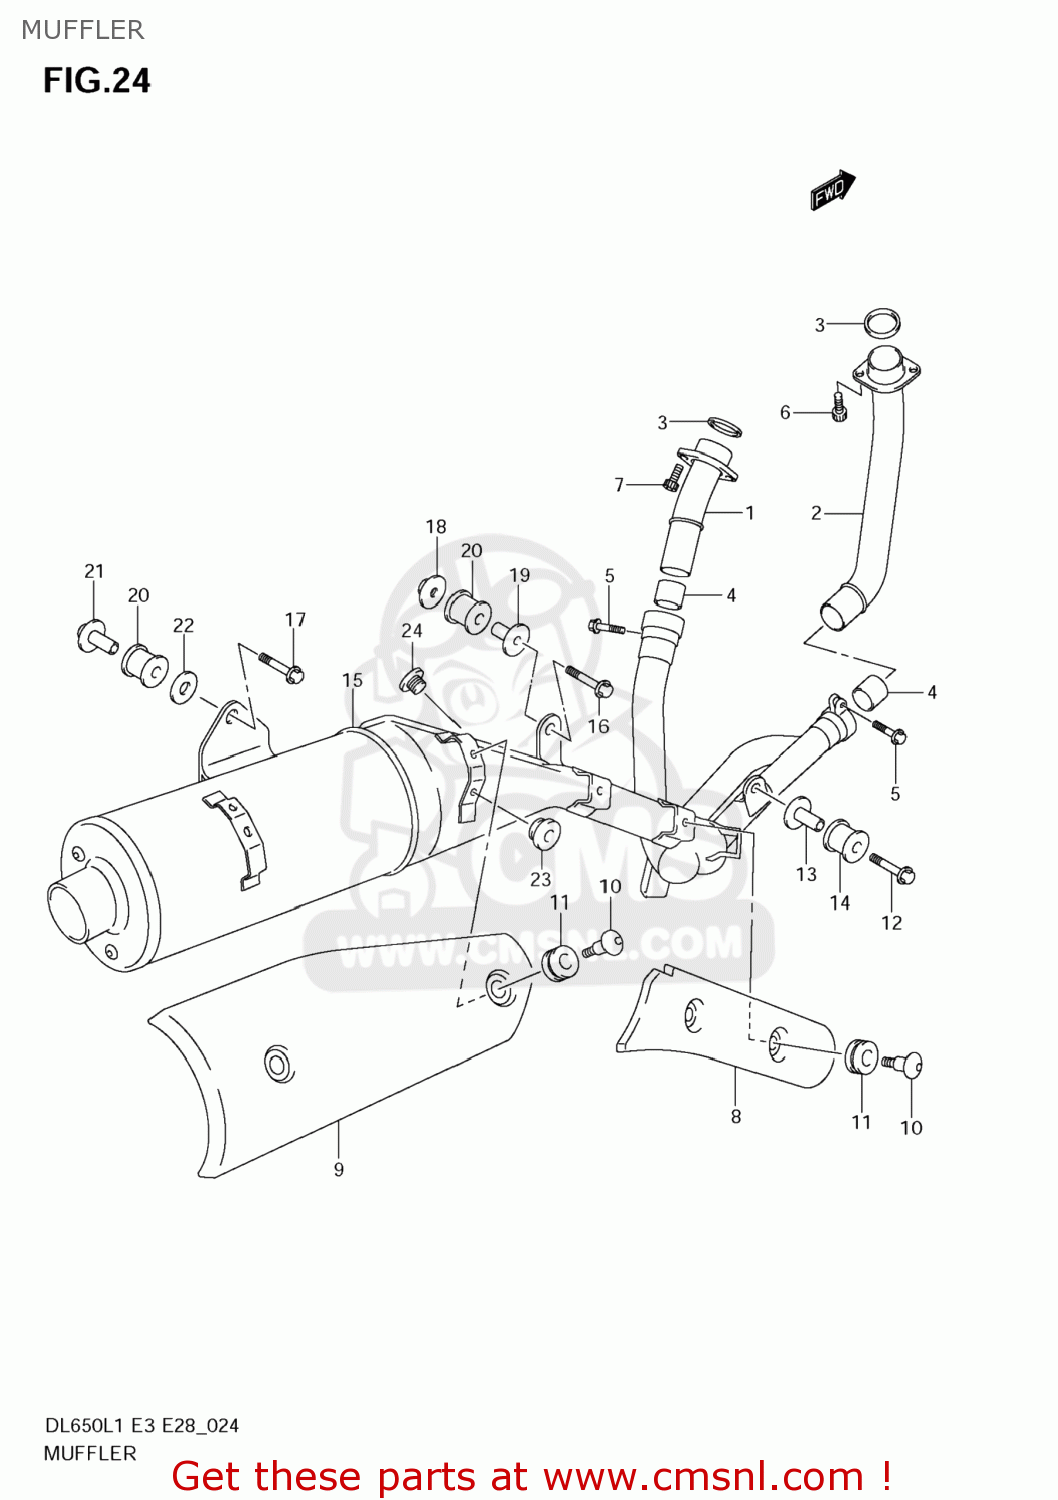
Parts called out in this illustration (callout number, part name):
1	PIPE,EXHAUST RR
2	PIPE,EXHAUST FR
3	GASKET,EXHAUST PIPE (NAS)
4	CONNECTOR,MUFFLER
5	BOLT(8X35)
6	BOLT(8X25)
7	BOLT
8	COVER,MUFFLER FR
9	COVER,MUFFLER
10	SCREW(6X20)
11	CUSHION
12	BOLT(8X45)
13	SPACER(8.6X12X24.2)
14	CUSHION
15	MUFFLER
16	BOLT
17	BOLT(8X45)
18	NUT,MUFFLER SUPPORT FR
19	SPACER(8.6X12X27.1)
20	CUSHION
21	NUT,MUFFLER SUPPORT
22	WASHER(8.5X33X1.5)
23	CUSHION
24	PLUG(18X8)
